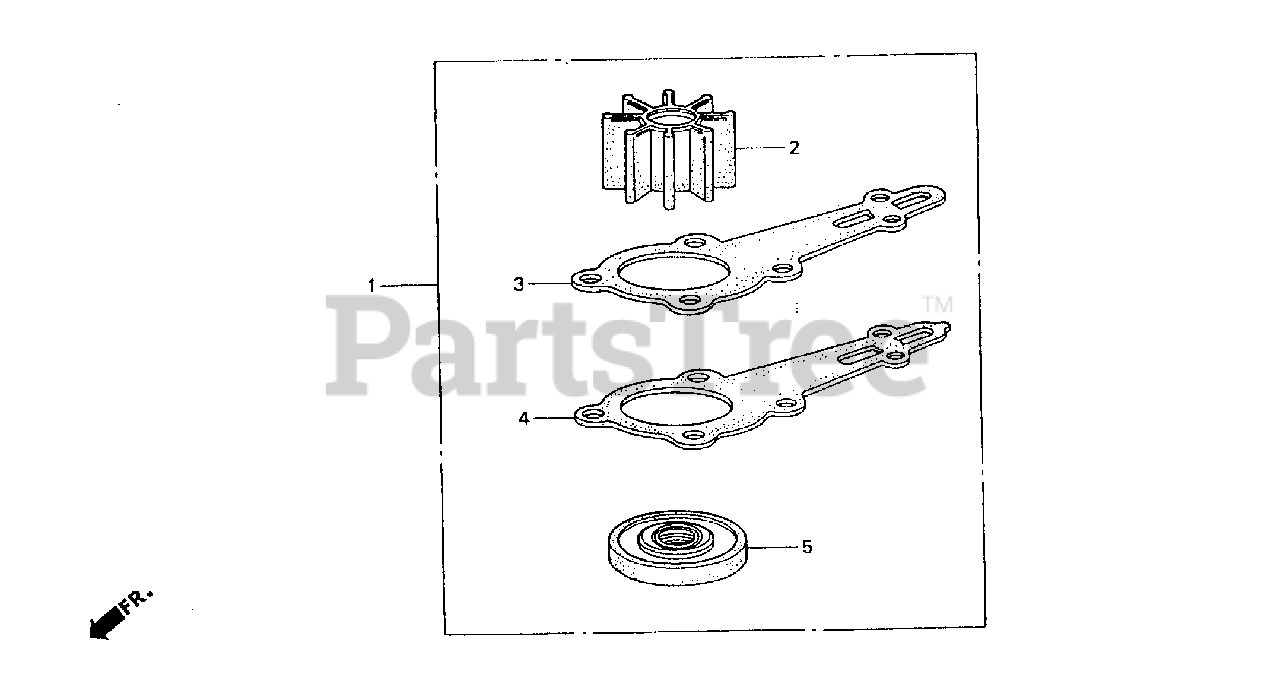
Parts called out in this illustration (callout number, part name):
1	IMPELLER KIT, WATER PUMP
2	IMPELLER, PUMP
3	GASKET A, IMPELLER
4	GASKET B, IMPELLER
5	SEAL, WATER (15MM) (NOK)
